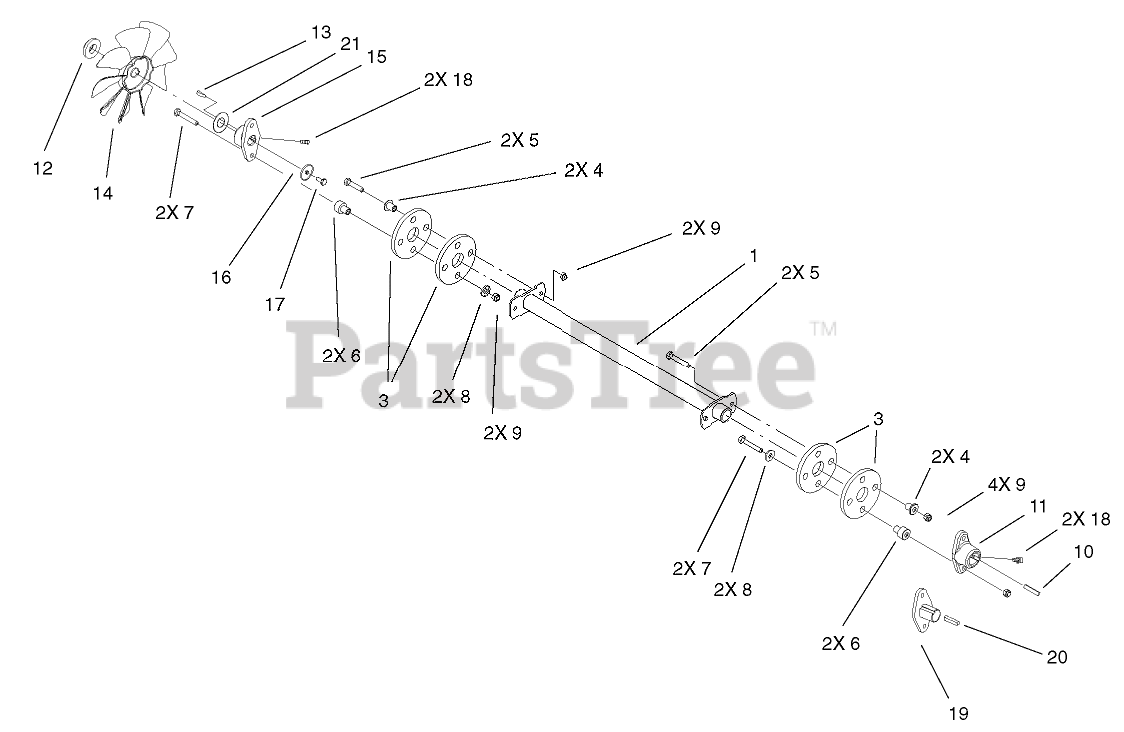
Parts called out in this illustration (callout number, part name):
1	SHAFT-DRIVE
3	COUPLING-RUBBER
4	SPACER
5	SCREW-HH
6	SPACER
7	SCREW-HH
8	WASHER-FLAT
9	NUT-LOCK, NI
10	KEY-SQUARE
12	SPACER-FAN
13	KEY-WOODRUFF
14	FAN-HYDRO
16	WASHER
17	SCREW-HH
18	SCREW-SET
21	WASHER - FAN
